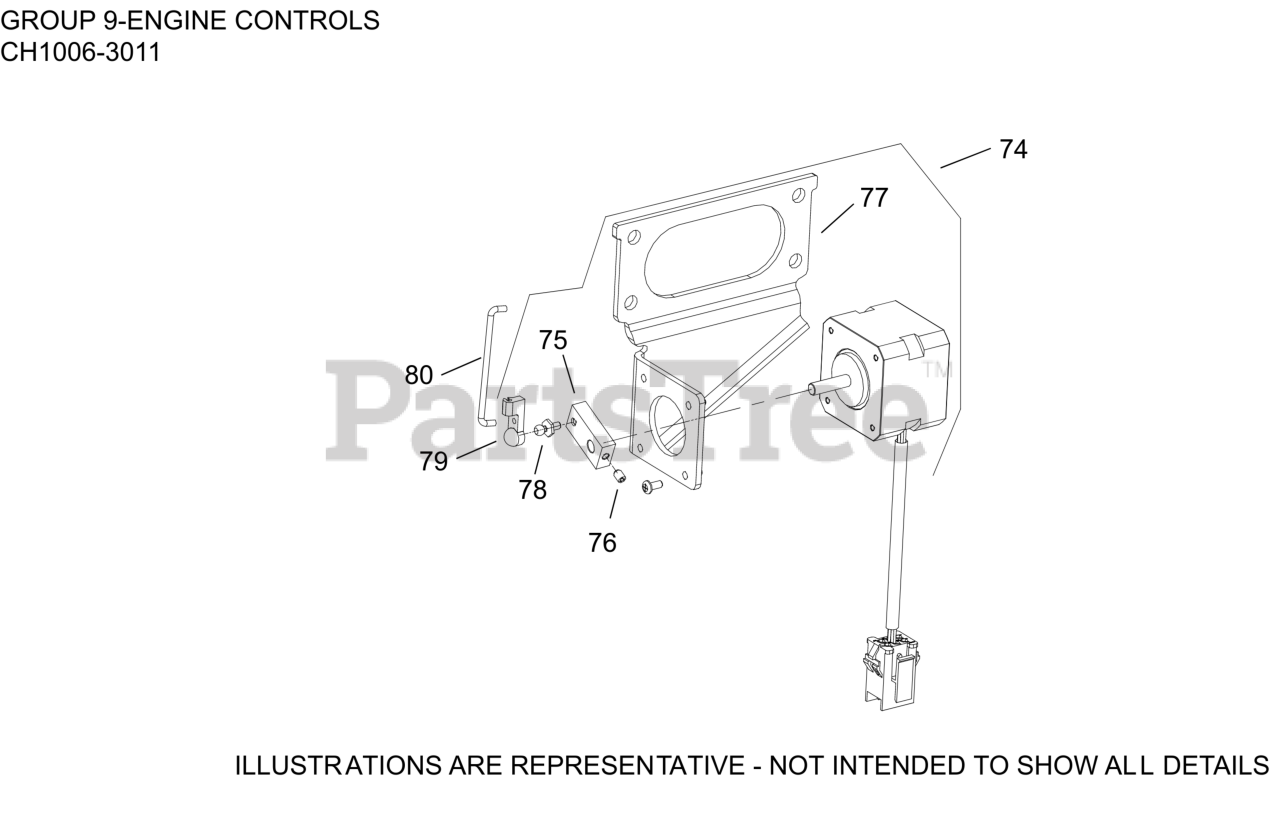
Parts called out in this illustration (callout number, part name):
74	ROTARY, STEPPER MOTOR ASSEMBLY
75	LEVER, STEPPER MOTOR
76	SCREW, SET #6-32
77	BRACKET, STEPPER MOTOR
78	SCREW, CUP JOINT GOVERNOR
79	CUP, BALL JOINT
80	LINKAGE, THROTTLE
